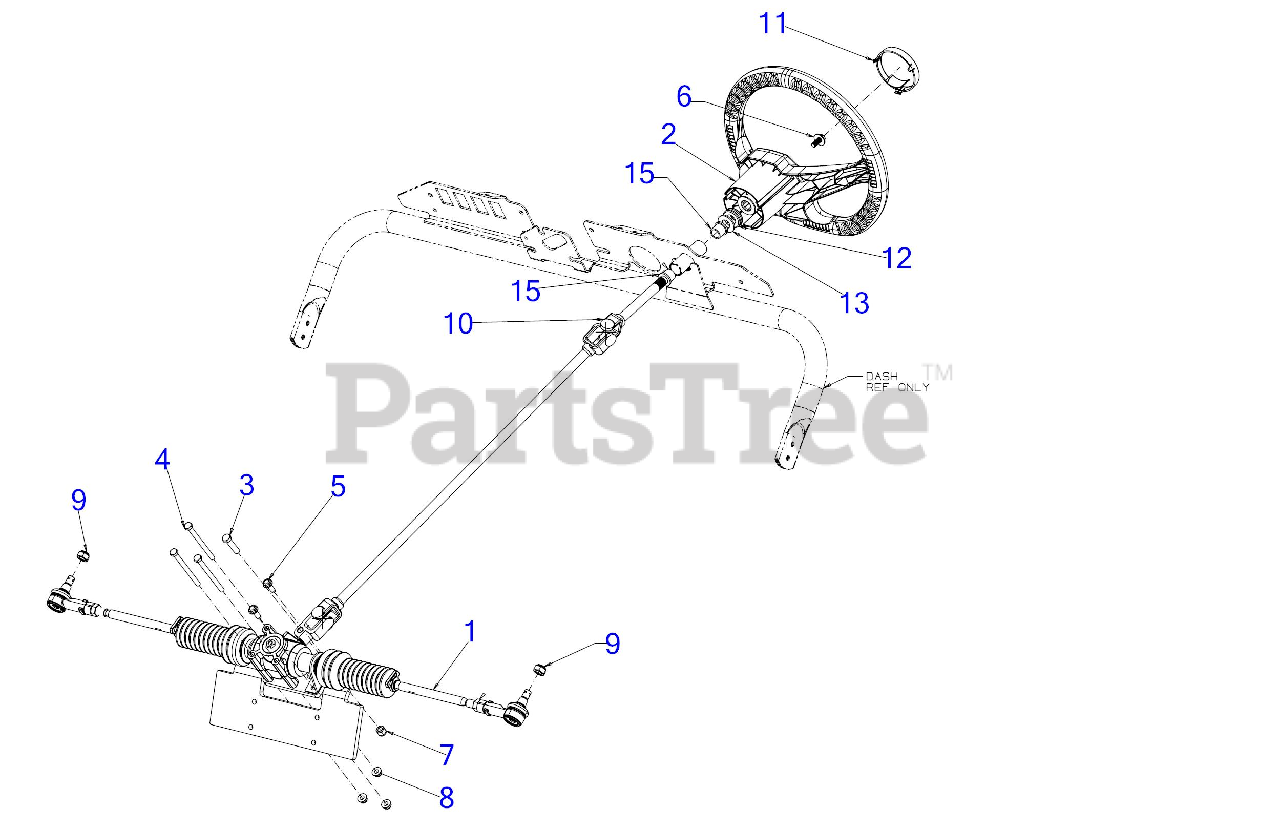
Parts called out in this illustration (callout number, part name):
1	BALL JOINT TIE ROD END
1	STEERING BOOT LTV
1	7" CABLE TIE
2	STEERING WHEEL 3 SPOKE
3	SCREW 3/8-16 x 1.50
4	SCREW 5/16-18 x 4.00 GR5
5	SCREW 5/16-18 x 1.00
6	SCREW 5/16-24 x .85 GR5
7	HEX NUT INS L-3/8-16
8	FLANGE LOCK NUT 5/16-18
10	STEERING SHAFT ASSEMBLY
11	STEERING WHEEL CAP
12	RUBBER GROMMET
13	FLAT WASHER .656 X 1.312 X .097
15	FLANGE BEARING
